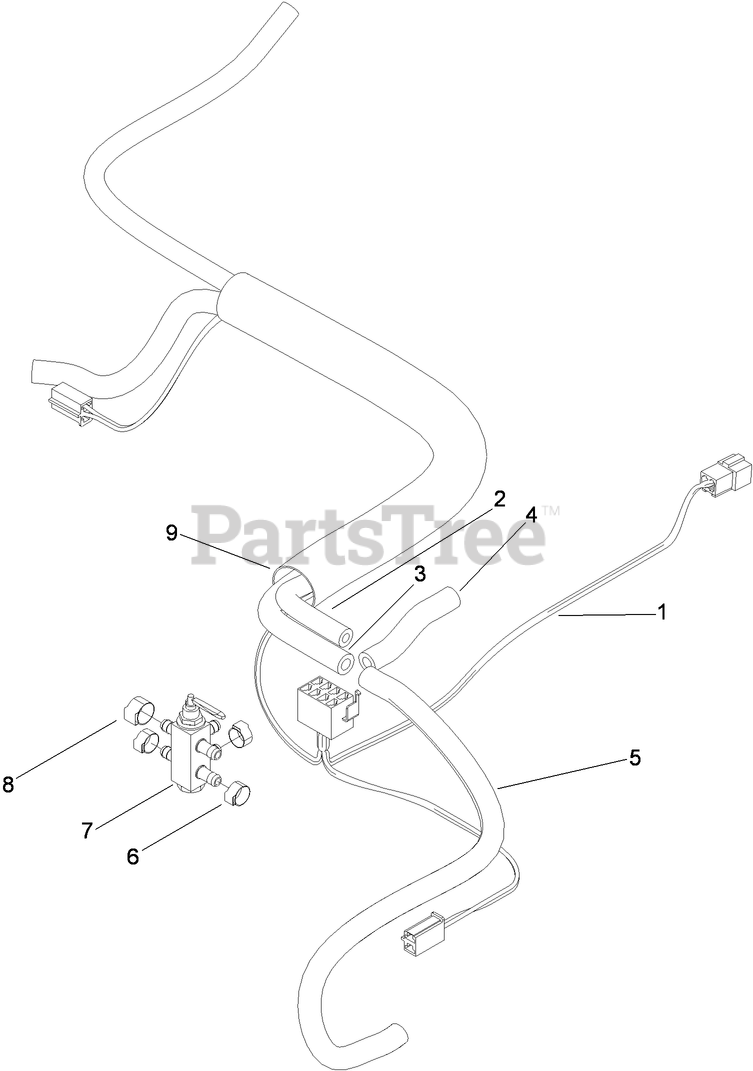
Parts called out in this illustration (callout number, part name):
1	WIRE HARNESS-DFI DUAL FUEL PUMPS
2	HOSE-FUEL
3	HOSE-FUEL
4	HOSE-FUEL
5	HOSE-FUEL
6	CLAMP-HOSE, FUEL
7	VALVE-FUEL, DUAL FLOW
8	CLAMP-HOSE, FUEL
9	SLEEVE-FABRIC
